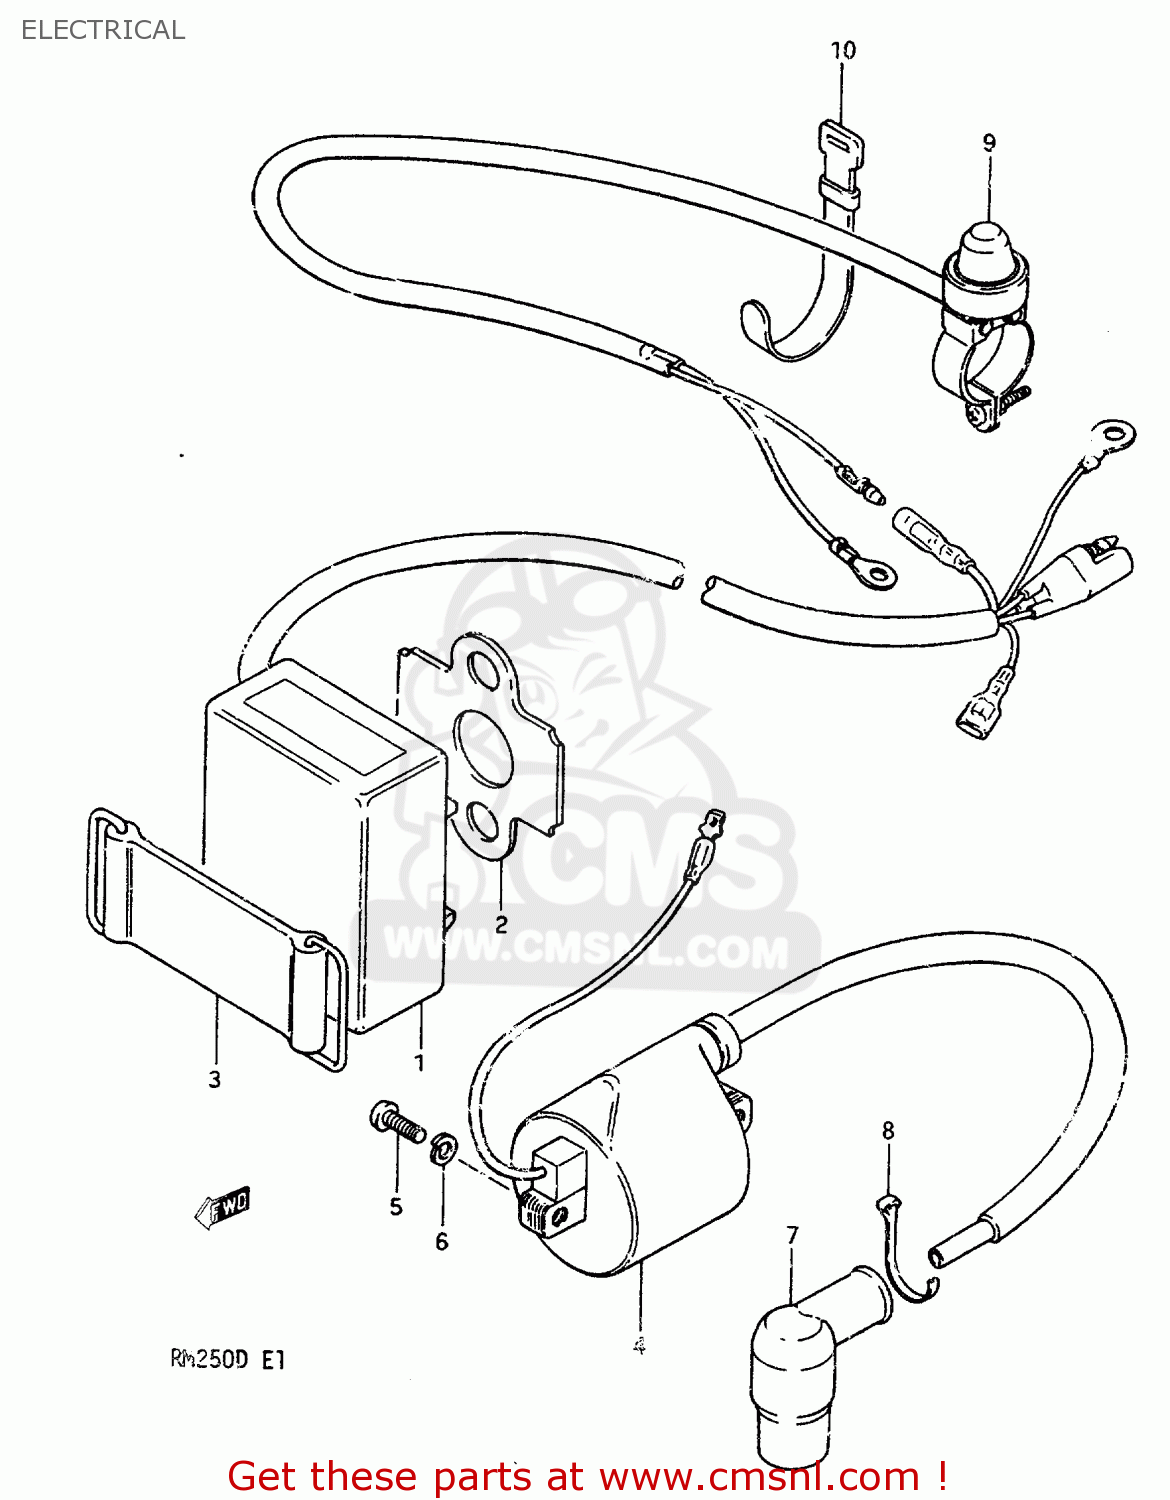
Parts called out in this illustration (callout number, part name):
1	CDI UNIT
2	PROTECTOR,CDI UNIT
3	BAND
4	COIL ASSEMBLY,IGNITION
5	SCREW
6	WASHER,LOCK
7	CAP,SPARK PLUG
8	CLAMP
9	SWITCH ASSEMBLY
10	CLAMP(L:120)
